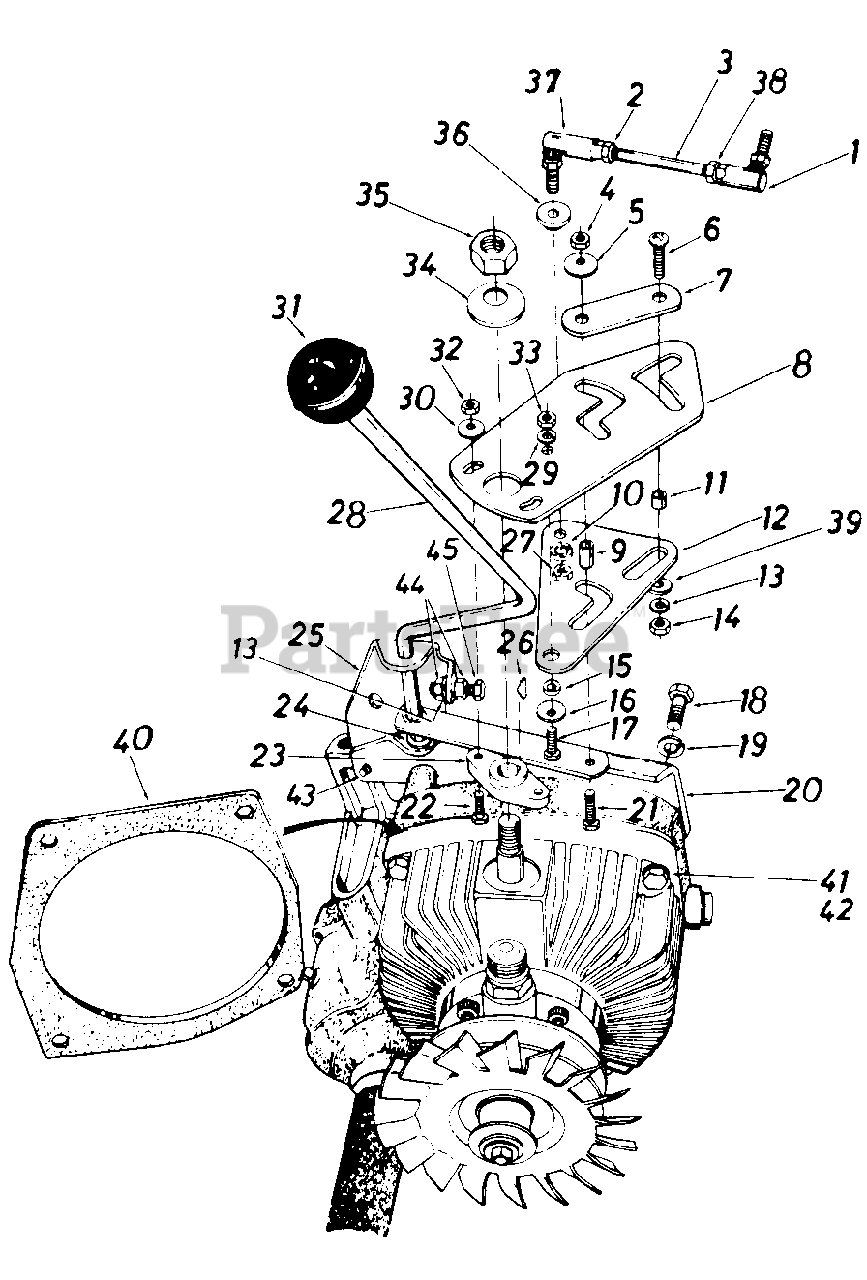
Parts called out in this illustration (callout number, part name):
1	Ball Joint Ass'y. 3/8-24 Thd.
2	Hex Nut 3/8-24 Thd. (L.H. Threads)
3	Control Rod 3/8-24 x 3.75"
4	Hex Nut 3/8-24 Thd.
5	Fl-Wash. .385" I.D. x .87" O.D.
6	Truss Mach. Scr. Phil. 5/16-18 x 1.00" Lg.
7	Locking Link
8	Pintle Main Control Plate
9	Spacer .377" I.D. x .500" O.D. x .830" Lg.
10	L-Wash. 3/8" I.D.
11	Spacer .315" I.D. x .500" O.D. x .350
12	Pintle Drive Plate
13	L-Wash. 5/16" I.D.
14	Hex Nut 5/16-18 Thd.
15	Spacer .38" I.D. x .227" Lg.
16	Fl-Wash. .385" I.D. x .87" O.D.
17	Hex Bolt 3/8-24 x 1.00" Lg.
18	Hex Bolt 3/8-16 x 1.0" Lg. (Grade 5)
19	L-Wash. 3/8" I.D.
20	Shift Lever Bracket
21	Hex Bolt 3/8-24 x 1.25" Lg.
22	Hex Bolt 1/4-28 x .75" Lg.
23	Pintle Hub
24	Nyliner .375" Dia. x .140
25	Shift Lever Bracket Upper
26	#5 Hi-Pro Key 1/8 x 5/8 Dia.
27	Hex Nut 3/8-24 Thd.
28	Shift Lever Ass'y.
29	L-Wash. 3/8" I.D.
30	Fl-Wash. .385" I.D. x .87" O.D.
31	Gear Shift Knob
32	Hex Nut 1/4-28 Thd.
33	Hex Nut 3/8-24 Thd.
34	Bell-Wash. .505" I.D. x 1.00" O.D.
35	Hex Nut 1/2-13 Thd.
36	Shld. Spacer .625" I.D.
37	Ball Joint Ass'y. 3/8-24 L.H. Thd.
38	Hex Jam Nut 3/8-24 Thd.
39	Fl-Wash. .330" I.D. x 1.25" O.D.
40	Gasket
41	Hex Bolt 3/8-16 x 2.75" Lg. (Gr. 5)
41	Hex Bolt 3/8-16 x 4.25" Lg. (Gr. 5)
42	Fl-Wash. .385" I.D. x .62" O.D.
43	Hex Wash. Hd. Self-Tap Scr. 1/4-20 x .50" Lg.
44	Hex Nut 5/16-24 Thd.
45	Hex Bolt 5/16-24 x 1.0" Lg.
